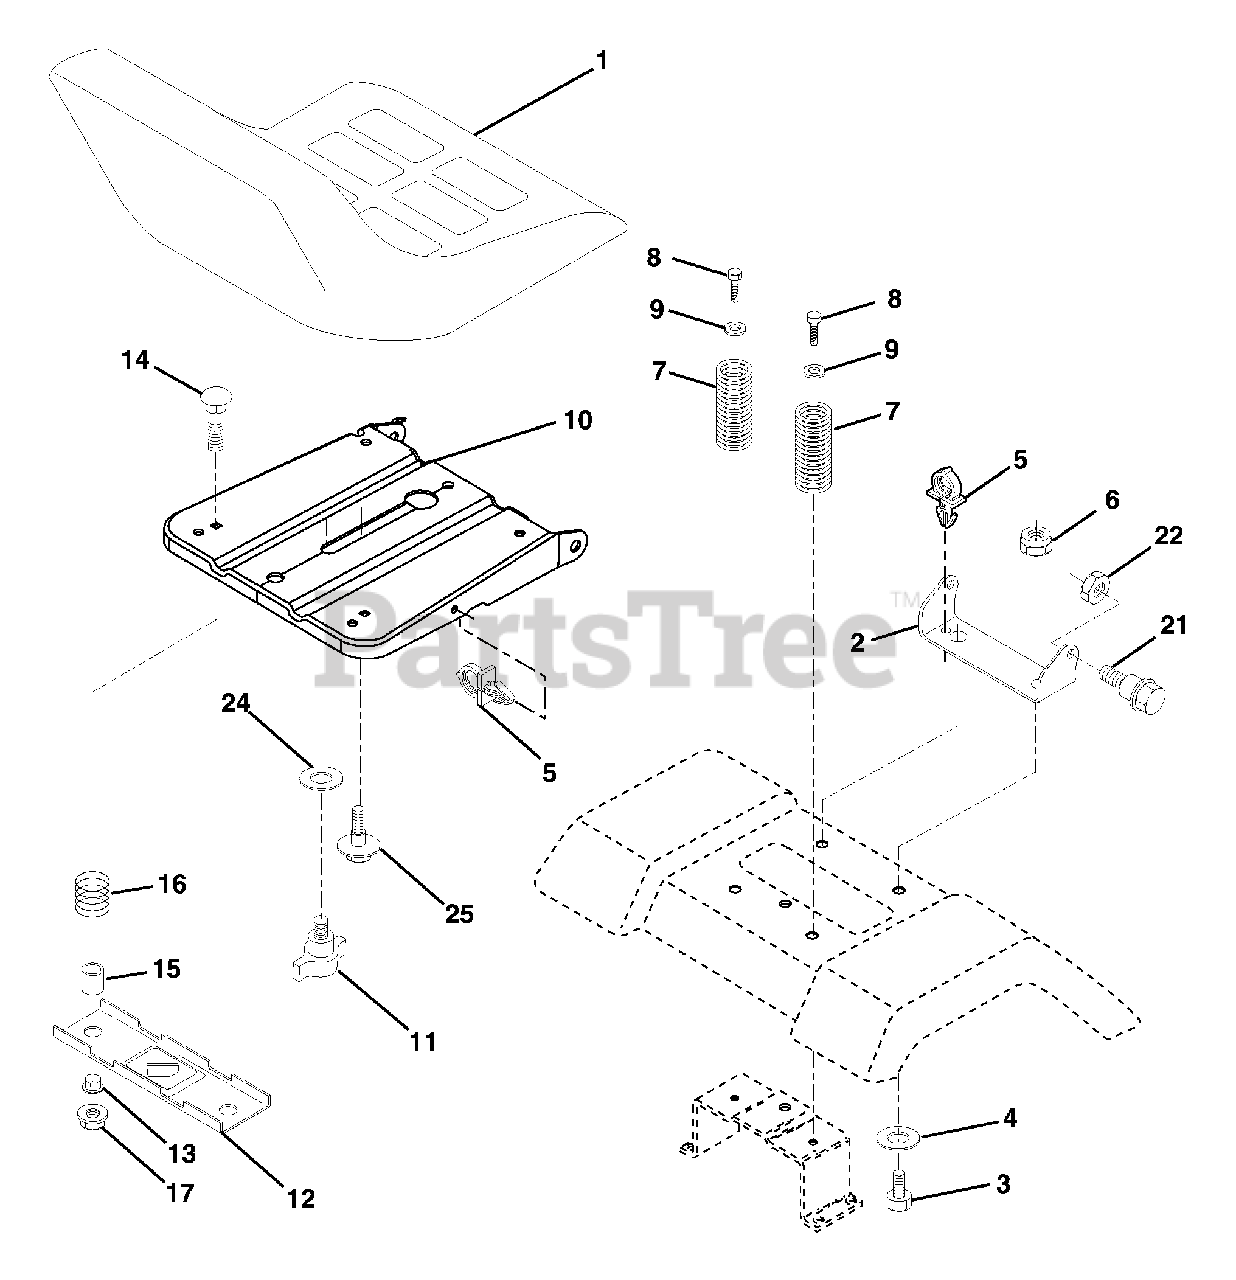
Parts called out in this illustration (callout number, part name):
1	Seat
2	Bracket Pivot Seat 8 720
3	Bolt Fin Hex 3/8-16 unc x 1
4	Washer 13/32 x 1 x 10 Ga.
5	Clip Push-In
6	Nut Hex w/Ins. 3/8-16 unc
7	Spring Seat Cprsn 2 250 Blk Zi
8	Screw 3/8-16 x 1.5 Smgml
9	Washer 13/32 x 1 x 14 Ga.
10	Pan Seat
11	Knob Seat
12	Bracket Mounting Switch
13	Bushing Snap Blk Nyl 50 Id
14	Bolt Rdhd Sqnk 1/4-20 x 1-1/2
15	Spacer Split 28x 88
16	Spring Cprsn
17	Nut Lock 1/4 Lge Flg Gr. 5 Zinc
21	Bolt Shoulder 5/16-18 unc
22	Nut Hex Lock W/Ins 5/16-18
24	Washer 17/32 x 1-3/16 x 12 Ga.
25	Bolt Shoulder 5/16-18 x 62
